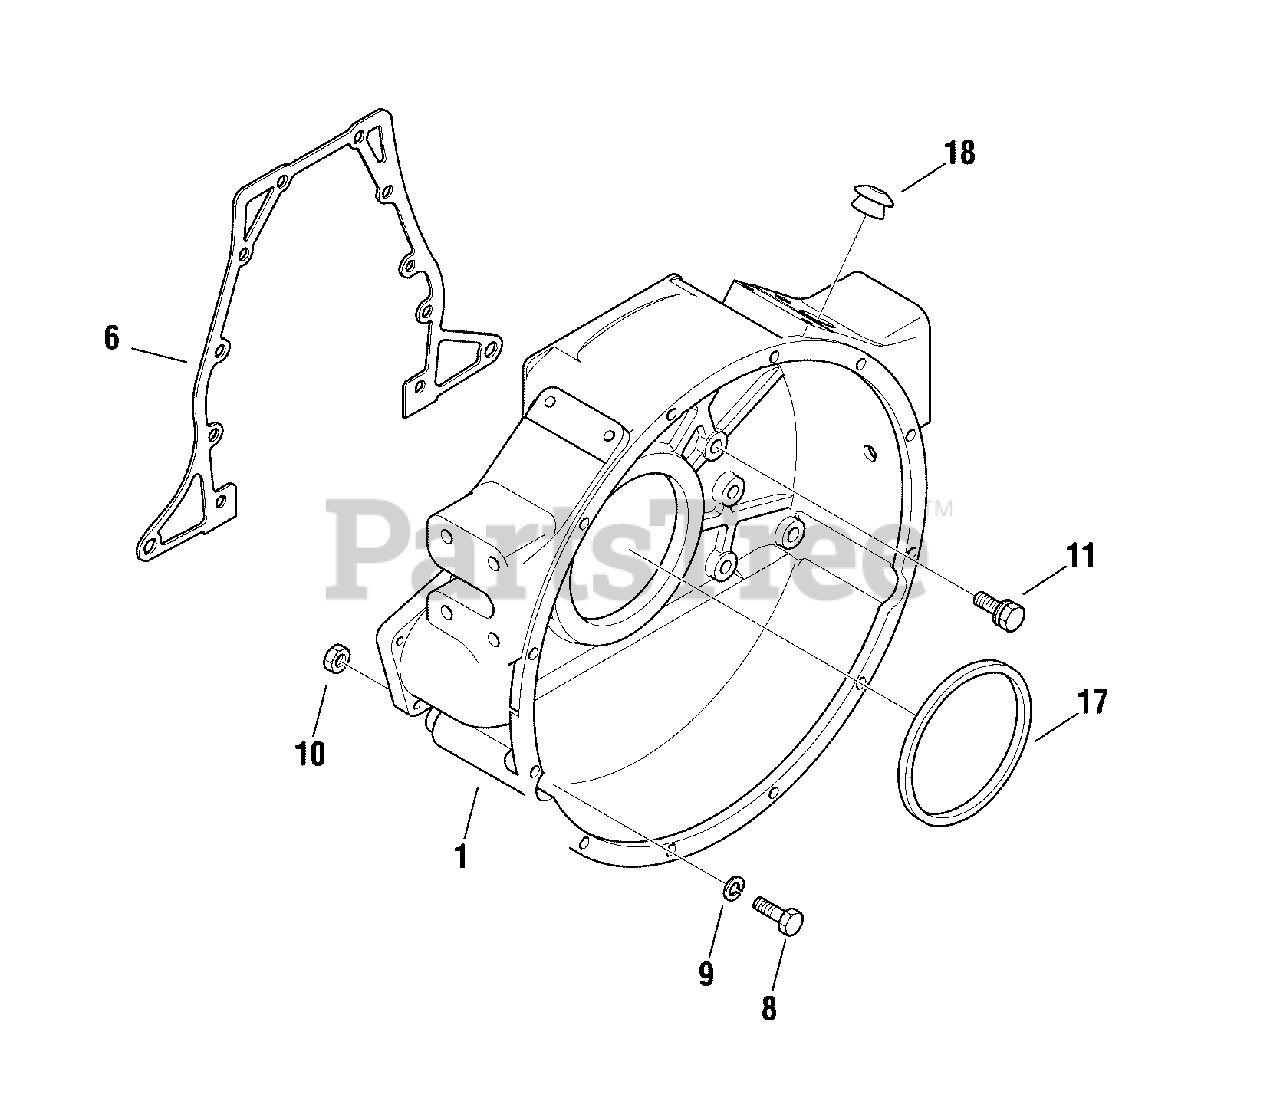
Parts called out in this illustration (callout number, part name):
1	* HOUSING, FLYWHEEL
6	GASKET, F/W COVER
8	* BOLT
9	* WASHER, SPRING
10	* NUT, HEX
11	* BOLT
17	SEAL, OIL
18	* PLUG, RUBBER
